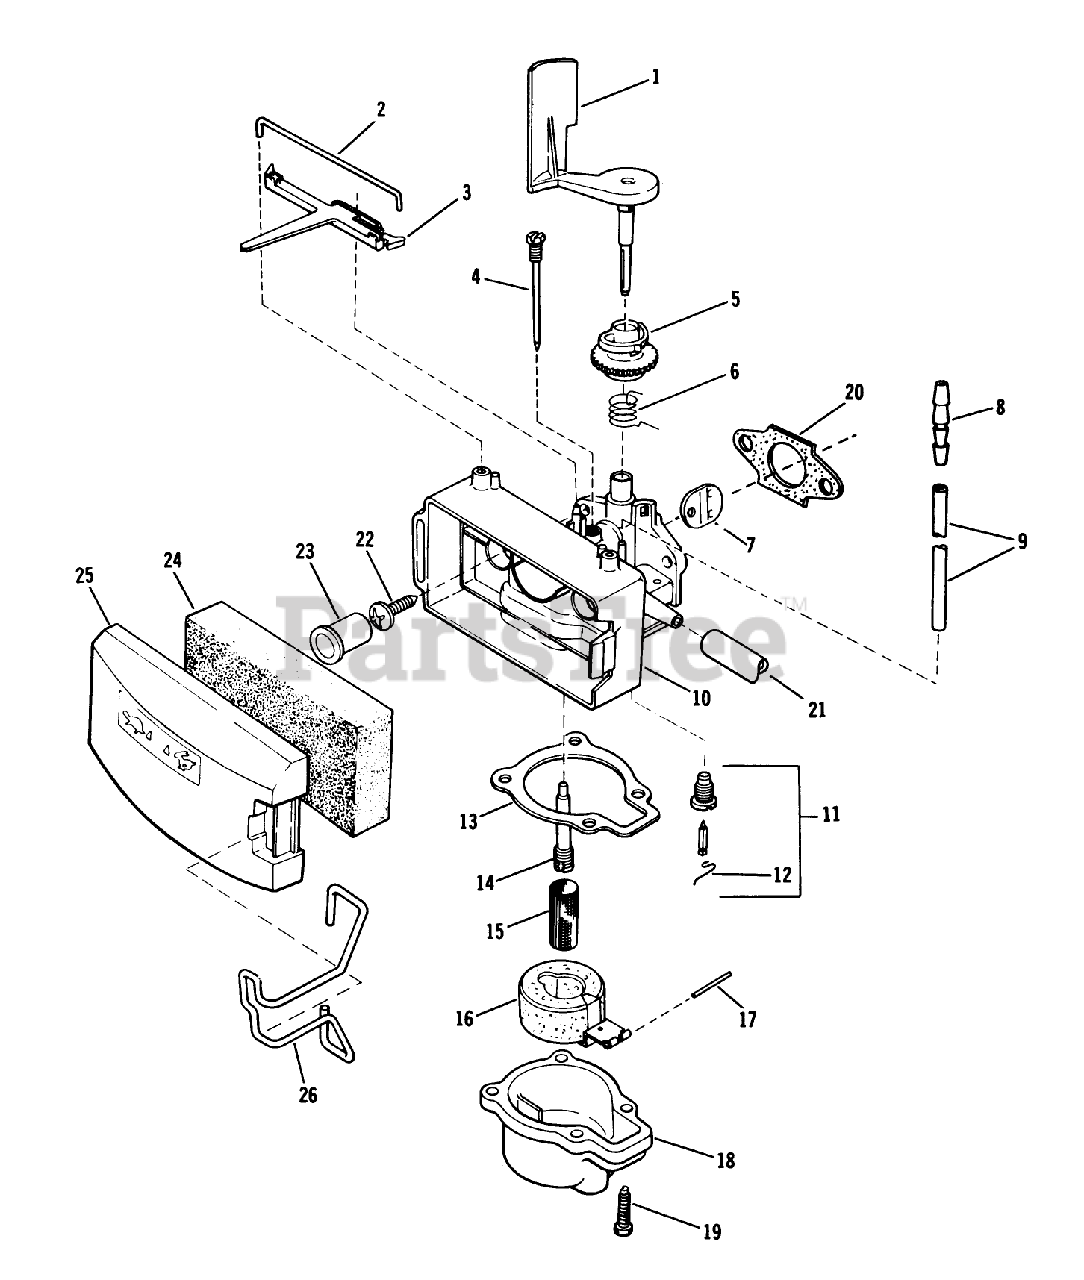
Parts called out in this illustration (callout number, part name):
2	RETAINER
3	LEVER S
4	NEEDLE ADJ. AY S
5	COLLAR-ADJUST, AIRVANE
6	SPRING,THROTTLE S
7	DISC S
8	REDUCER-CONNECTOR
9	TUBING S
10	CARB BODY S
15	FILTER-FUEL VS
19	SCREW-HH
20	GASKET CARB S
21	GAS LINE
22	SCREW
26	RETAINER-COVER, FILTER
